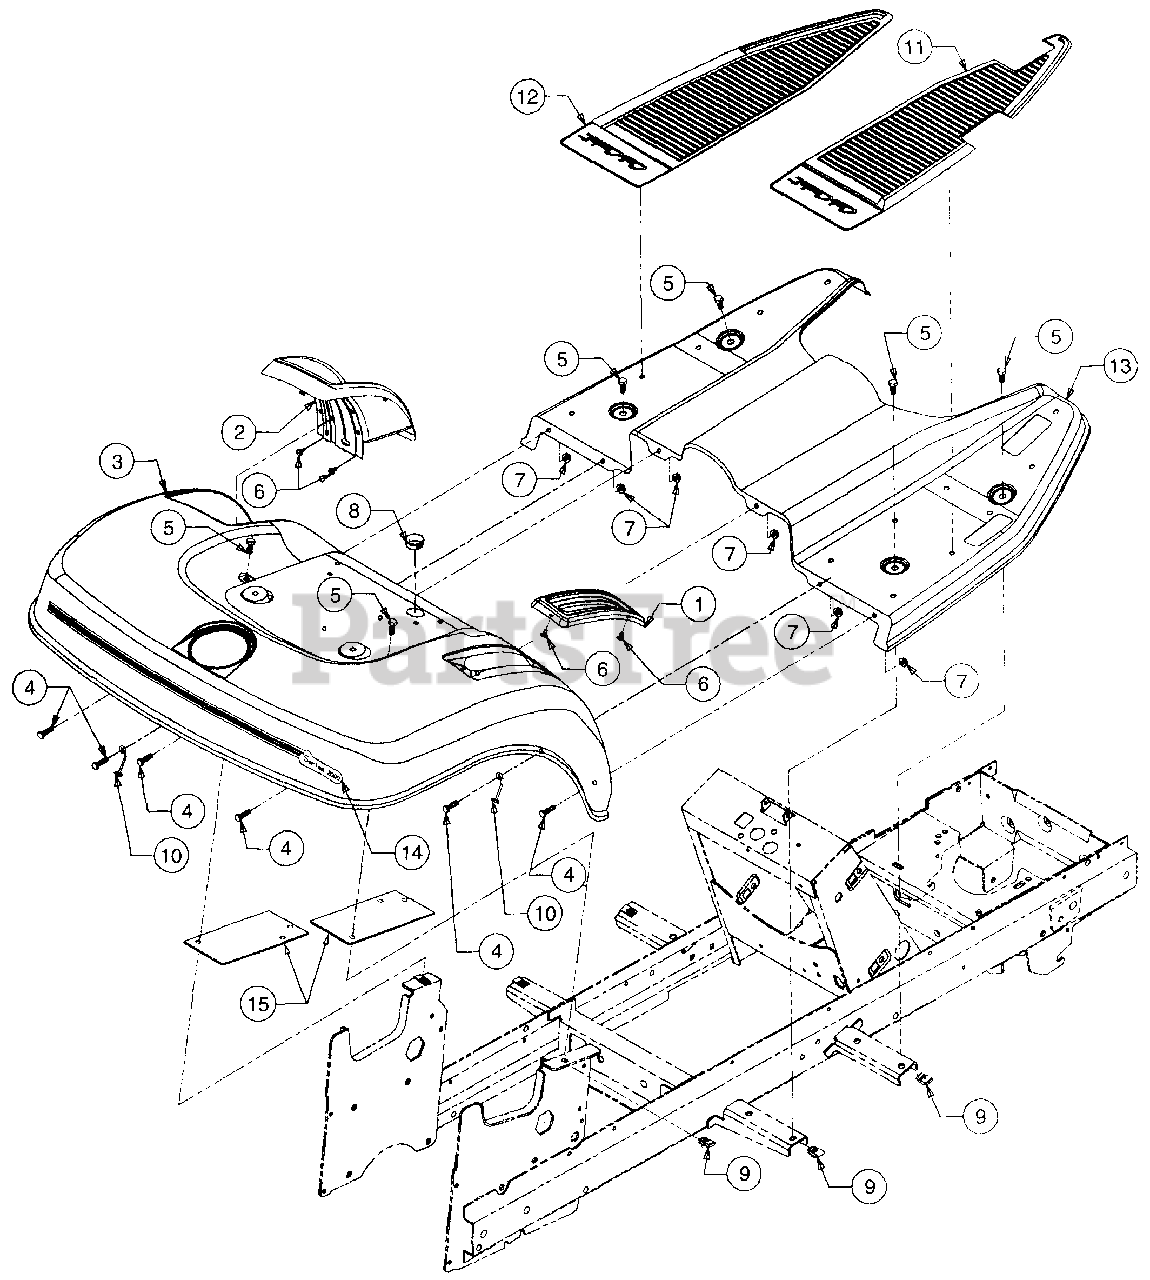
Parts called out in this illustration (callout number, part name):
1	Cover, 6-Speed Shifter
2	Cover, Implement Lift
3	Fender
4	Screw, Hex Cap, 1/4-20 x .62
5	Screw, Hex Wash Hd Tapp 1/4-20 x 1.0
6	Screw, Hex Tapp, #10 x .38 Lg
7	Nut, Hex Flange Lock, 1/4-20
8	Bushing, Snap, 7/8 ID
9	U-Nut, 5/16-18
10	Retainer, Hook
11	Pad, RH Foot
12	Pad, LH Foot
14	Graphic, Rear Fender
